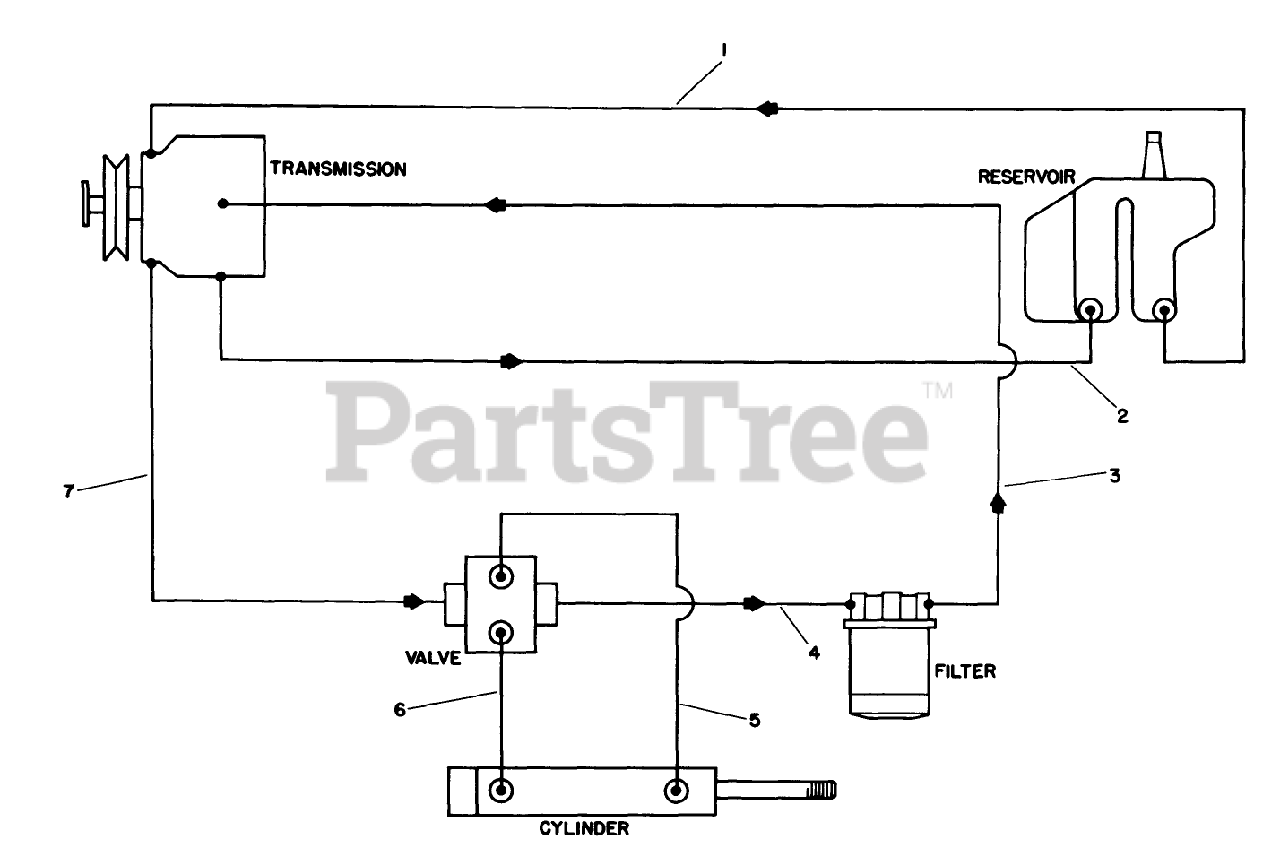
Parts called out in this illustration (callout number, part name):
1	HOSE ASM
2	TUBE ASM
3	HOSE ASM
4	HOSE ASM
5	HOSE ASM
6	HOSE ASM
7	HOSE ASM
